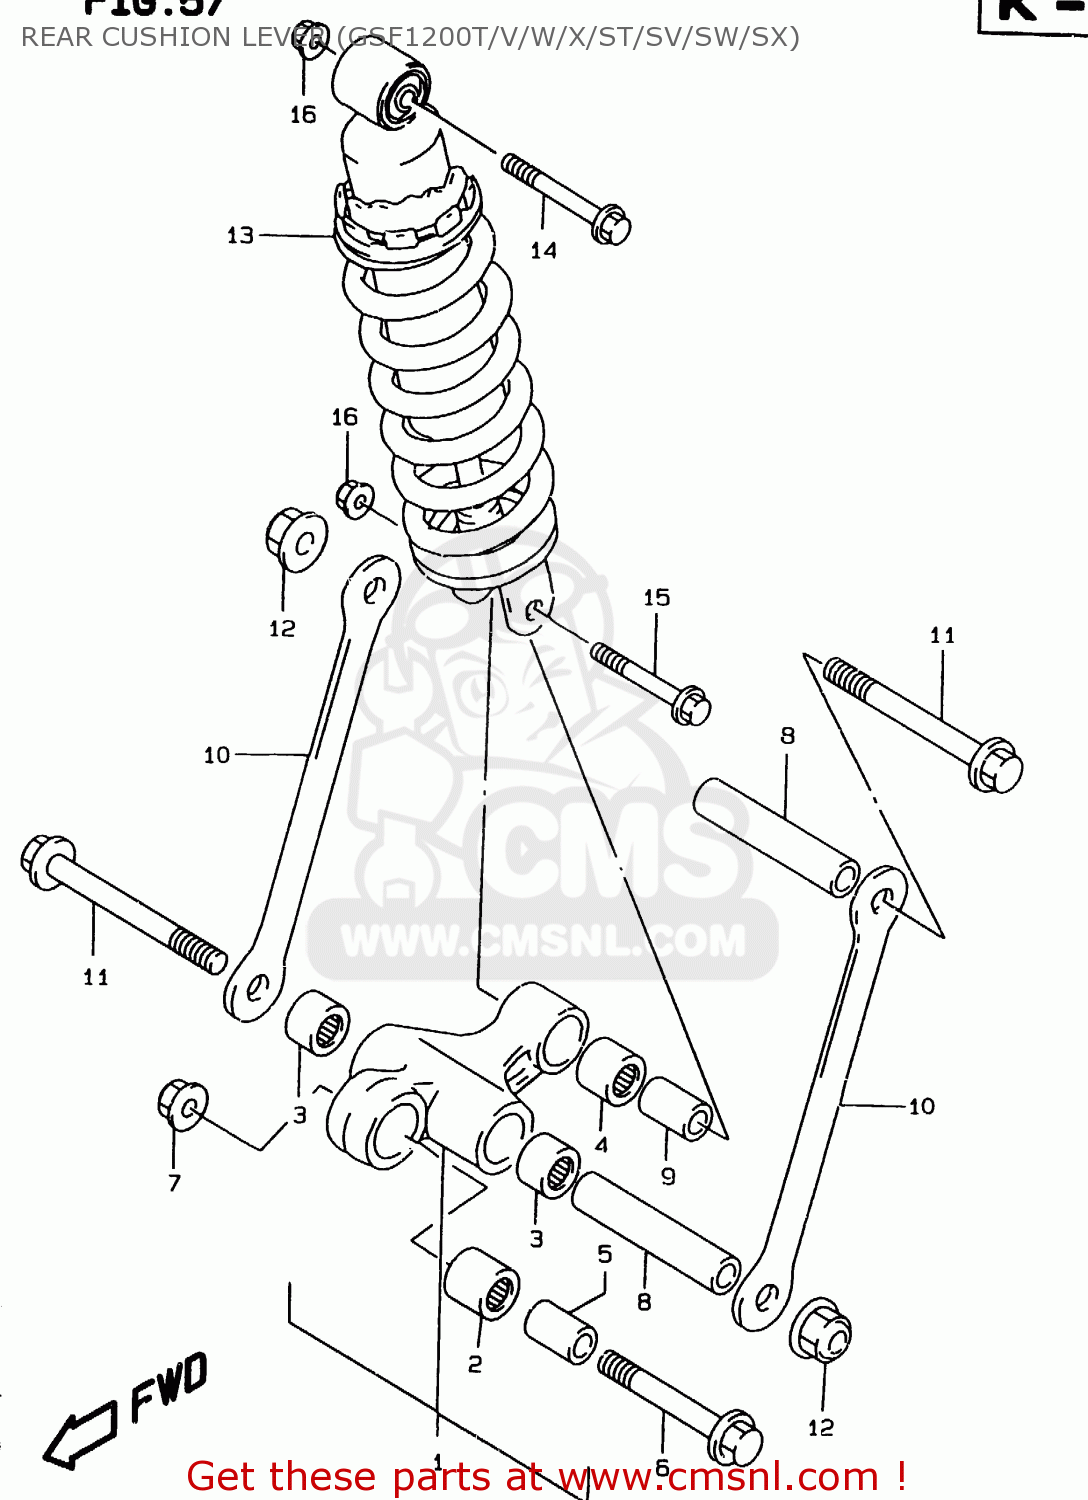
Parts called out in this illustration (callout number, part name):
1	LEVER SET,RR CUSHION
2	BEARING(20X27X26)
3	BEARING(17X24X25)
4	BEARING(17X24X26)
5	SPACER,RR CUSHION LEVER FR
6	BOLT,CUSHION LEVER FR
7	NUT 12MM
8	SPACER(12X17X85)
9	SPACER,RR CUSHION LEVER
10	ROD,RR CUSHION LEVER
11	BOLT(12X115)
12	NUT 12MM
13	ABSORBER,RR SH
14	BOLT(10X50)
15	BOLT(10X54)
16	NUT
